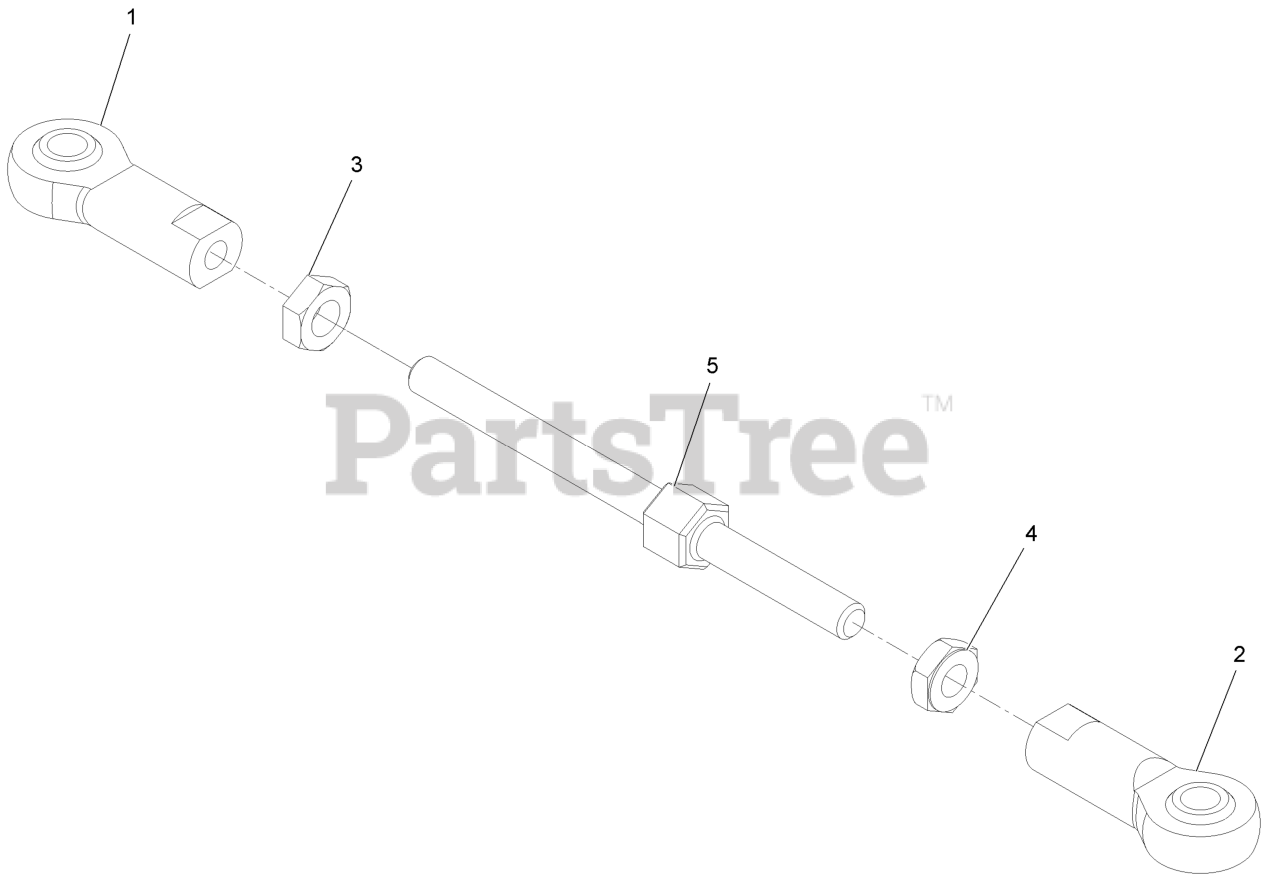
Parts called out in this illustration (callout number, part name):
1	ROD END-BALL JOINT
2	JOINT-BALL, LH
3	NUT-JAM
4	NUT-JAM
5	ROD-VERTICAL ADJUST
